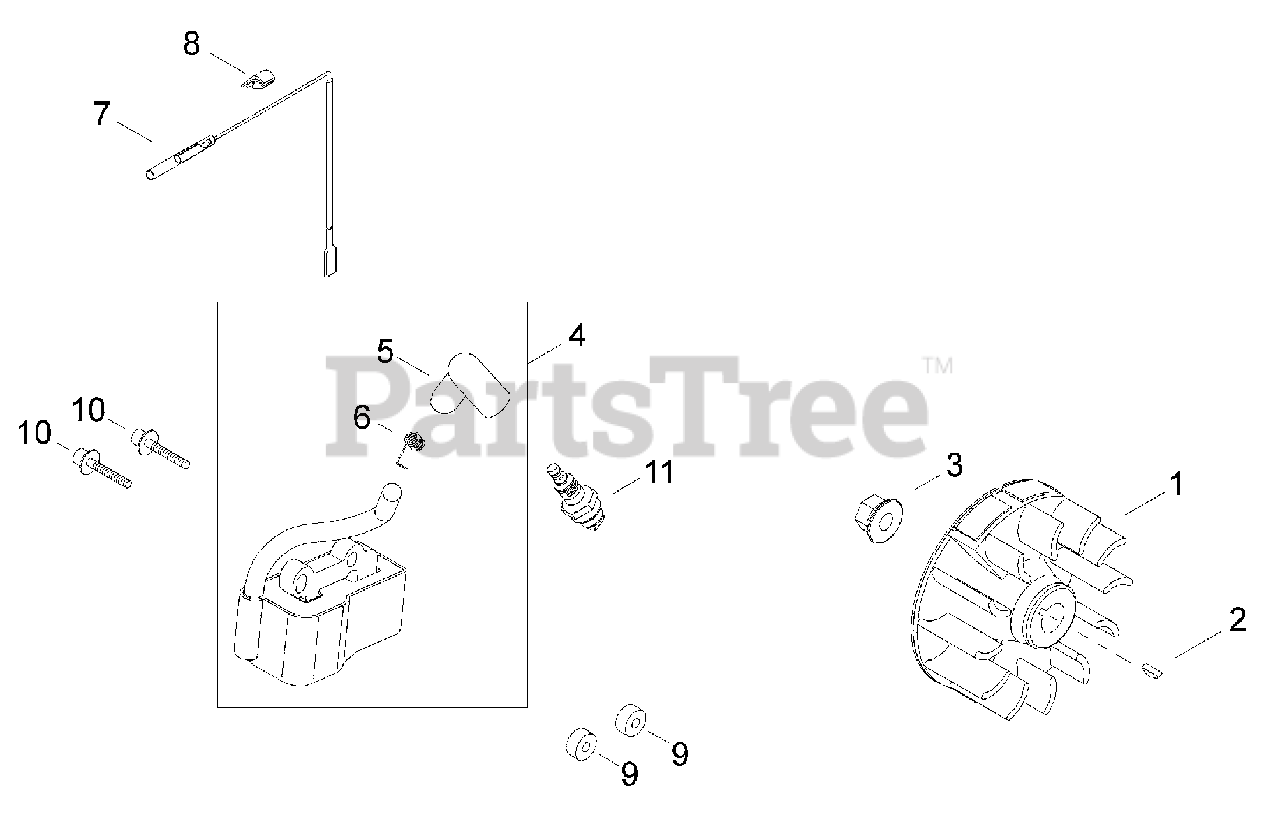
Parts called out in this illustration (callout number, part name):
1	FLYWHEEL
2	KEY - 3X10
3	NUT - 8
4	IGNITION COIL ASSY
5	CAP, SPARK PLUG
6	TERMINAL, SPARK PLUG CAP
7	LEAD - IGNITION
8	GROMMET
9	INSULATOR
10	SCREW - 4X26
11	SPARK PLUG -- CMR-5H
